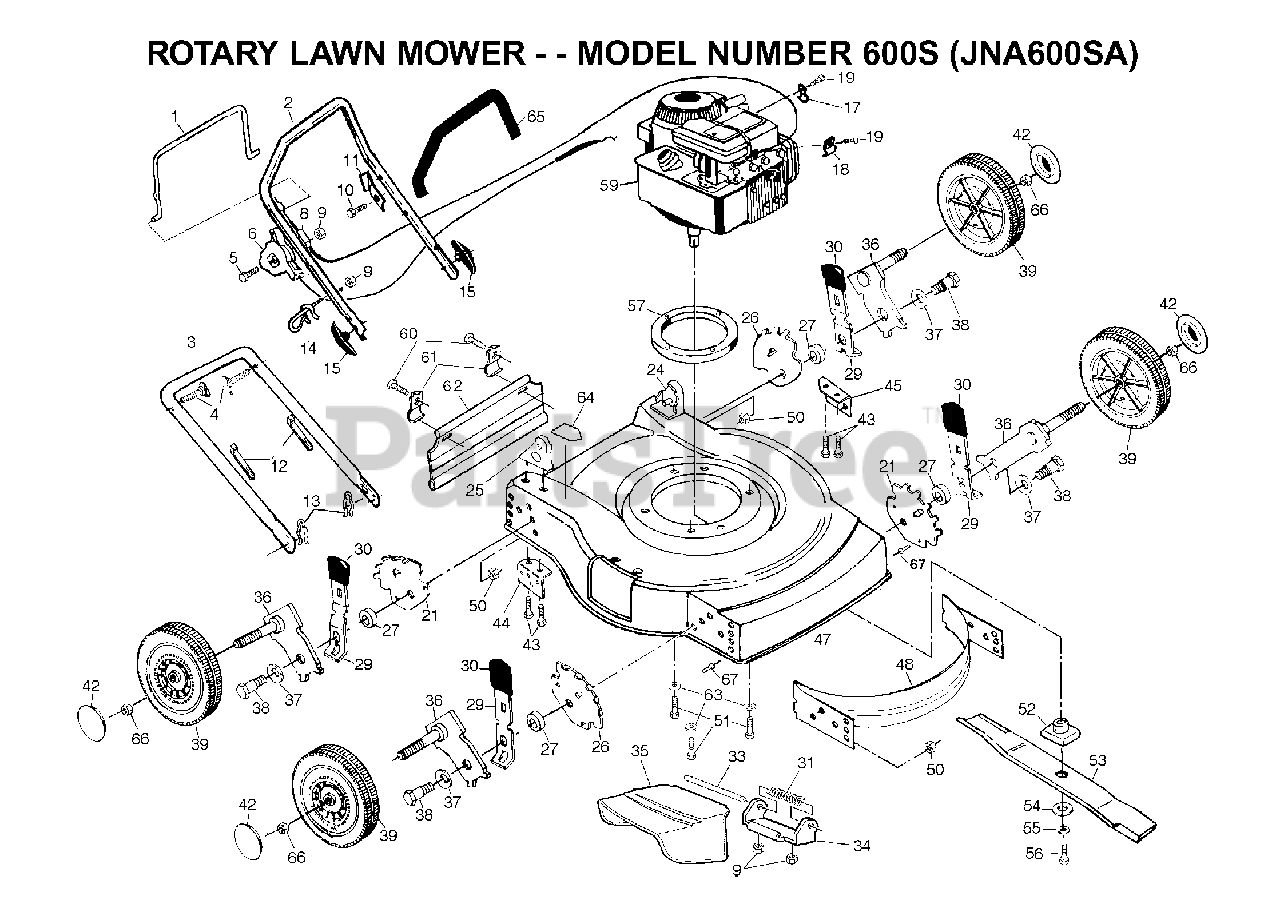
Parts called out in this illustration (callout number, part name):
1	CONTROL BAR/BLACK
4	HANDLE BOLT
6	THROTTLE CONTROL
8	ENGINE ZONE CONTROL CABLE
9	NUT
10	TAPPING SCREW
11	BRACKET UPSTOP
12	TIE GUIDE
13	HAIRPIN COTTER
15	HANDLE KNOB
17	CABLE CLAMP(ENGINE)
18	GUIDE CLIP PM
19	SCREW.HEX.HEAD.WASHER.10-16
21	BRACKET.WHL.ADJ.L
24	HANDLE BRACKET ASM. LH
25	HANDLE BRACKET ASM. RH
26	BRACKET.WHL.ADJ.R
27	RP SPACER HT ADJ
29	SELECTOR SPRING
31	SPRING PM
33	ROD.HINGE.COMBI-C
34	BRACKET PM
36	AXLE, REAR
37	BELLEVILLE WASHER
38	BOLT
43	SCREW 5/16-18
50	LOCKNUT PM
52	BLADE ADAPTOR
53	%20"BLADE (FOR MODELS 50/51)
54	WASHER,HARDEN
55	LOCKWASHER
56	SCREW, HEX HD 3/8-24 X 1-3/8
60	TAPPING SCREW
61	BRACKET DEFL PM
62	REAR SKIRT
65	GRIP.HANDLE.FOAM
66	HEX FLANGE LOCKNT
67	RIVET BLIND
